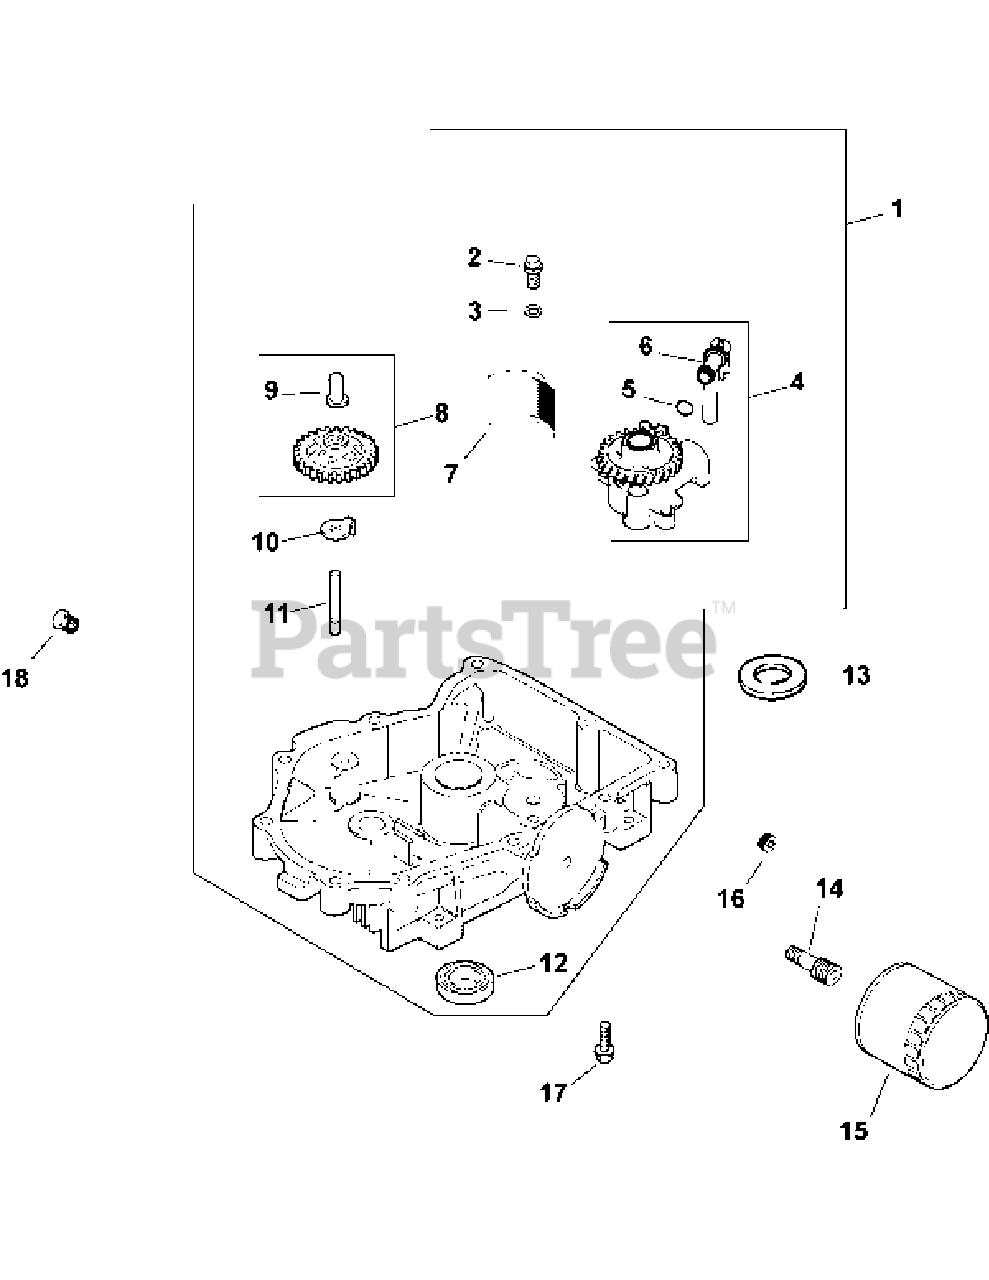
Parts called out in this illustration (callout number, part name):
1	OIL PAN ASSEMBLY
2	SCREW, FLG THD FRM M6X1.0X25
3	WASHER, FLAT 6 MM
4	KIT, OIL PUMP ASSEMBLY
5	O-RING, OIL PICK-UP
6	TUBE, OIL PICK-UP
8	KIT, GOVERNOR GEAR W/PIN
9	PIN, GOVERNOR REGULATING
11	SHAFT, GOVERNOR GEAR
14	NIPPLE, OIL FILTER
16	PLUG, PIPE CTSK 3/8"
17	SCREW, FLG M8X1.25X45
18	PLUG, HD PIPE 3/8"
